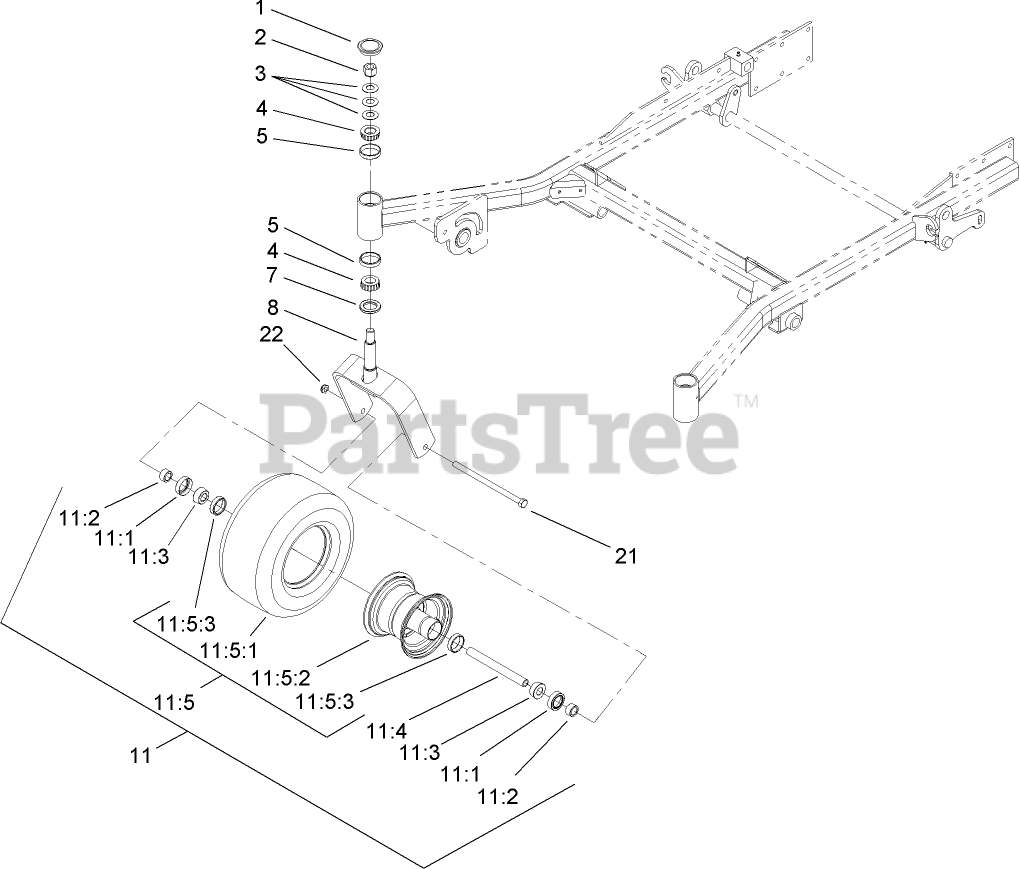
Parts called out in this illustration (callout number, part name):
1	CAP-GREASE
2	NUT-LOCK, NI
3	WASHER-BELLVILLE
4	BEARING-CONE, TAPERED
5	BEARING-CUP, TAPERED
7	SEAL-GREASE
8	CASTER-FORK
11	CASTER WHEEL ASM
11:1	SEAL-BEARING
11:2	SPACER-BEARING
11:3	BEARING-CONE, TAPER
11:4	SPACER-CASTER, FRONT
11:5	Wheel and Tire ASM
11:5:3	BEARING-CUP
21	Screw-HH
22	NUT-LOCK, NI
